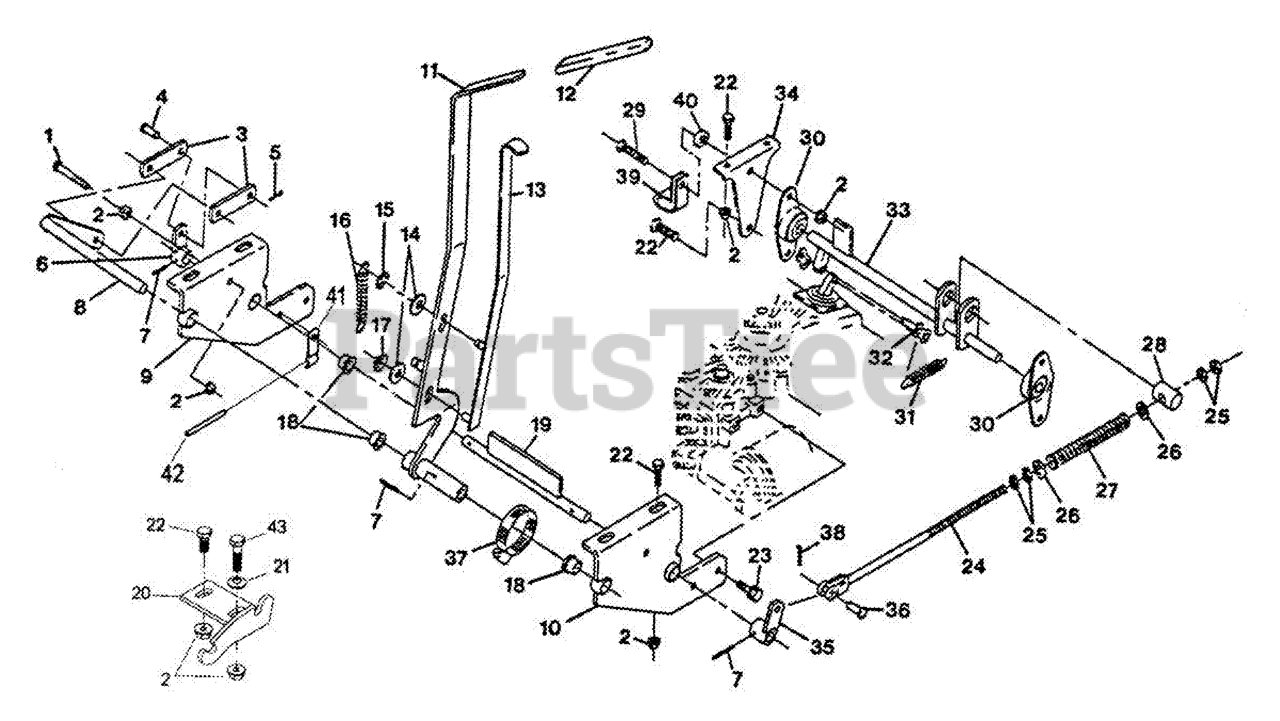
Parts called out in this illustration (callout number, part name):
1	SCREW-HH
3	LINK,BRAKE PLTD
4	PIN-CLEVIS
5	PIN-COTTER
6	WLD,CONTROL ARM
8	PIVOT - BRKT/LEVER
10	WLD,TRANSAXLE SUPPORT RH
11	LEVER,PARK BRK W/DECAL
12	GRIP-LEVER
14	WASHER-PLAIN
15	RING-RETAINING, EXT
16	SPRING,BRAKE HANDLE
17	NUT,PUSH
18	BEARING-CONTROL
19	WLD,BUTTERFLY
20	WLD,BRAKE QUADRANT
21	WASHER-SPRING
22	SCREW-HH
23	SCREW-HHF
24	LINKAGE,BRAKE
25	NUT-HJ
26	WASHER-FLAT
27	SPRING,COMPRESSION
28	PIN,TRUNION
29	SCREW-HH
30	FLANGE MTG, SIDE
32	LINK,CONNECTING
33	WLD,BRAKE JACKSHAFT
35	WLD,BRAKE CONTROL ARM
36	PIN-CLEVIS
37	CLAMP-HOSE
38	PIN-COTTER
40	SPACER,CLUTCH ANCHOR
41	SPRING,DUMP VALVE
42	ROLLPIN PLTD
43	SCREW-HH
